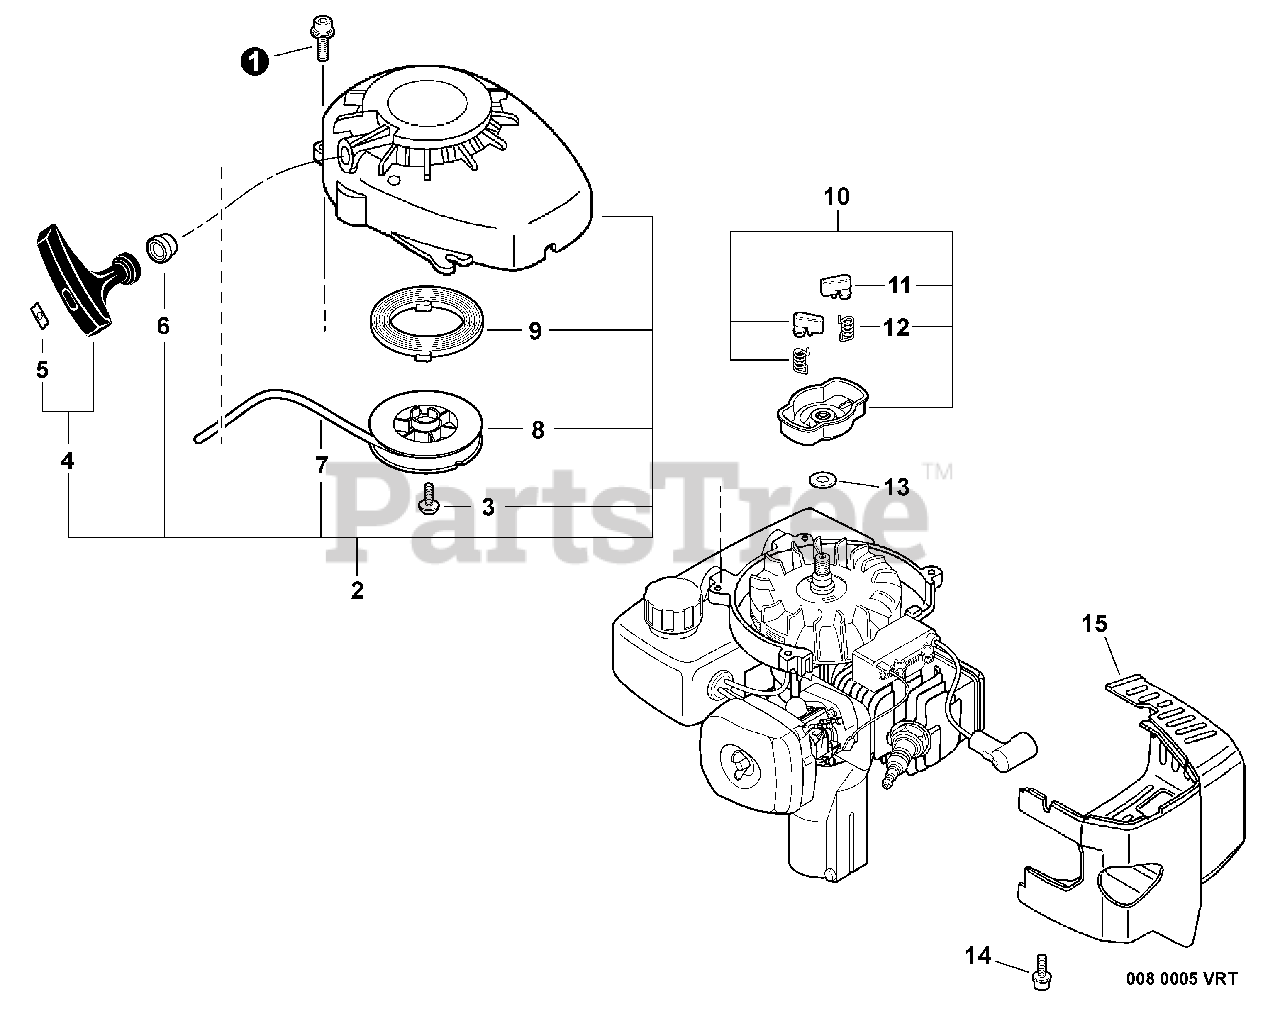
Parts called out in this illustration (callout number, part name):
1	SCREW - 4X16
2	STARTER ASSY - GRAY
4	GRIP, STARTER
5	RETAINER, ROPE
6	GUIDE, ROPE
7	ROPE, STARTER - 3X890
8	REEL, ROPE
9	SPRING, REWIND
10	STARTER PAWL ASSY
11	PAWL, STARTER - BLACK
12	SPRING, RETURN
13	LOCKWASHER - 8
14	SCREW - 4X18
15	COVER, ENGINE - GRAY
